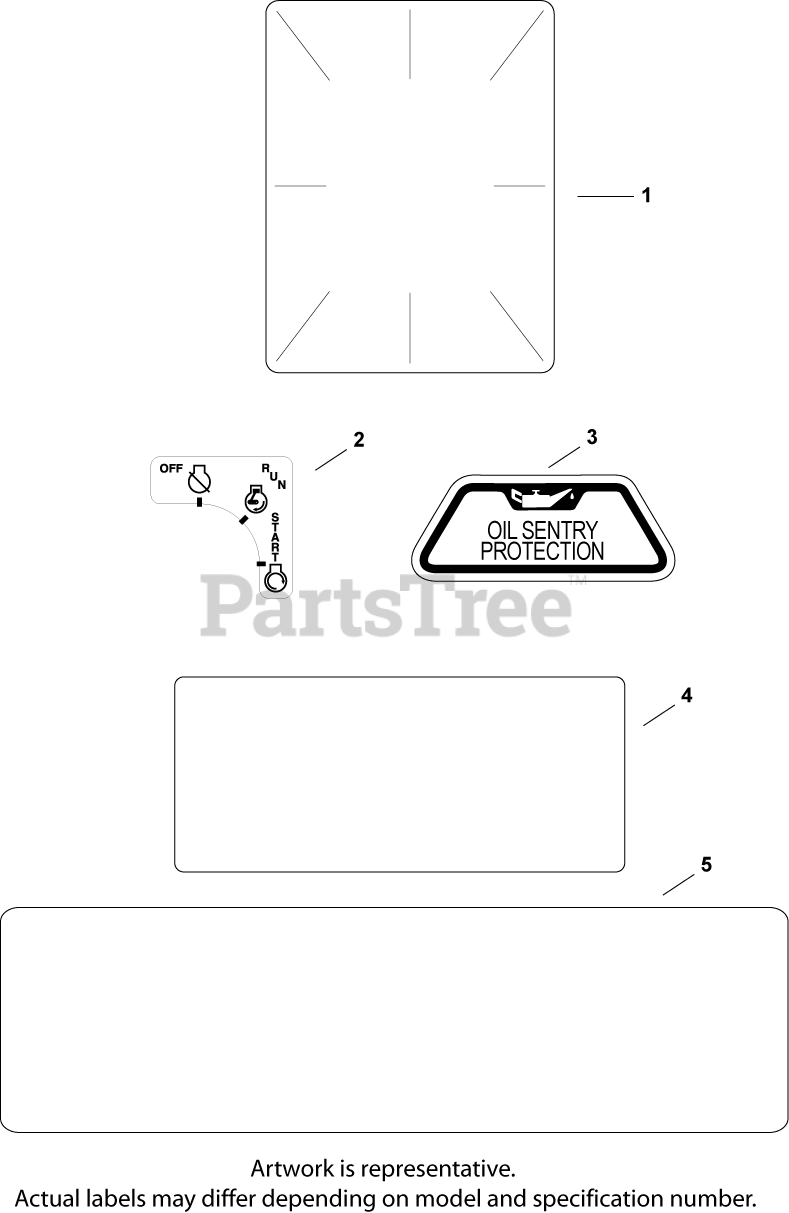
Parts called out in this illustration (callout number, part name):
1	DECAL, CLEAR LAMINATE USE 25 113 70-S
2	DECAL, KEY SWITCH
3	DECAL, OIL SENTRY - (#DSC)
4	DECAL, REPL ENGINE(NONCERT)
5	DECAL, 20 HP - DISCONTINUED
